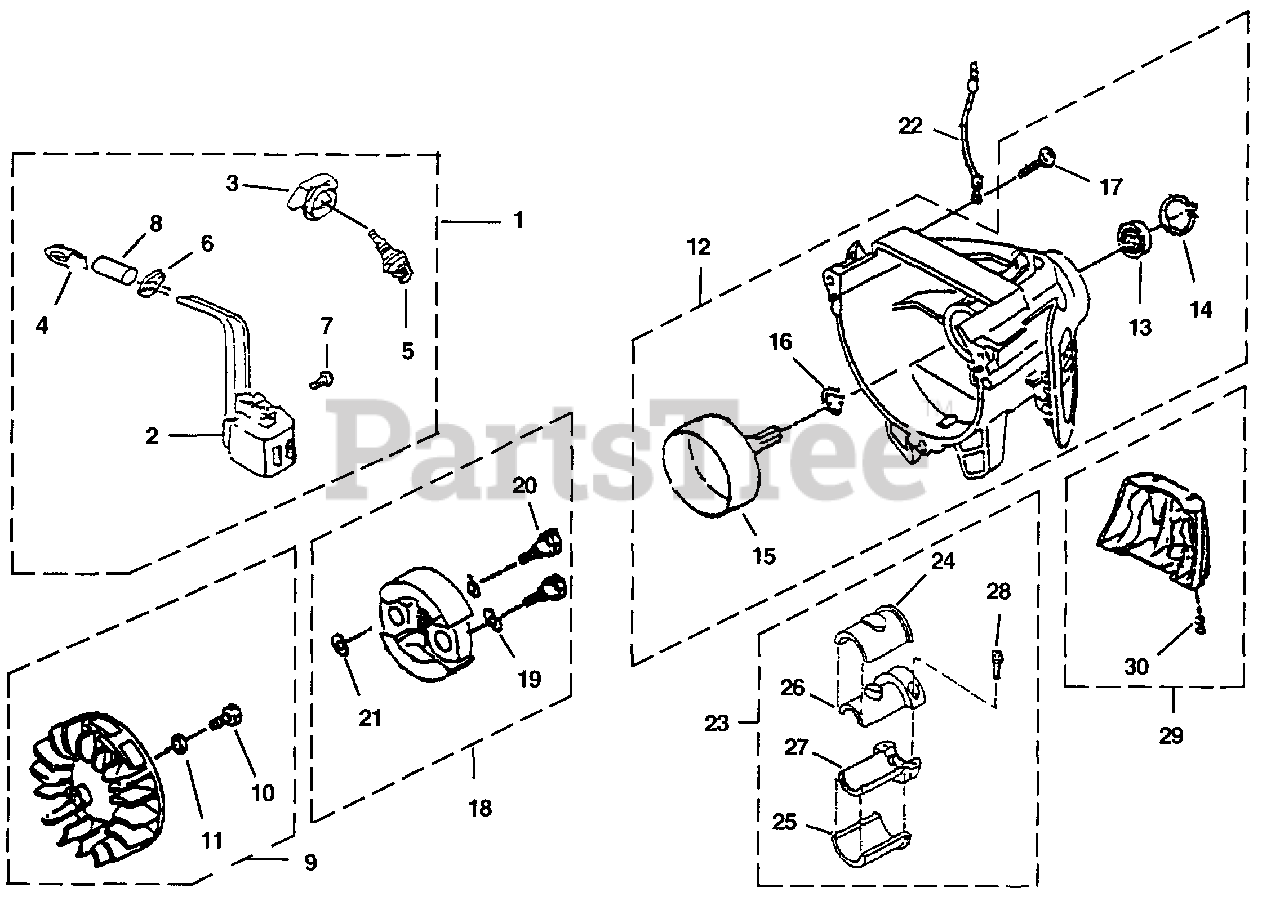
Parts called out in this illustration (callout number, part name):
1	IGNITION KIT
2	MODULE - Ignition
3	CAP - Plug
4	SPRING - Plug Cap
5	SPARK PLUG
7	SCREW ASSEMBLY (M4 x 20)
9	ROTOR ASSEMBLY
10	BOLT ASSEMBLY (M6 x 16)
12	CLUTCH HOUSING
13	BEARING - Ball
14	SNAP RING - Inner
15	CLUTCH DRUM
16	SNAP RING - Outer
17	SCREW - Socket Hd (M5 x 20)
18	CLUTCH ASSEMBLY
20	BOLT - Clutch (M6 x 25)
23	DRIVESHAFT ISOLATOR ASSEMBLY
26	ISOLATOR
27	ISOLATOR
28	SCREW - Socket Hd (M5 x 18 SW)
29	ENGINE STAND
30	SCREW ASSEMBLY (M5 x 14)
